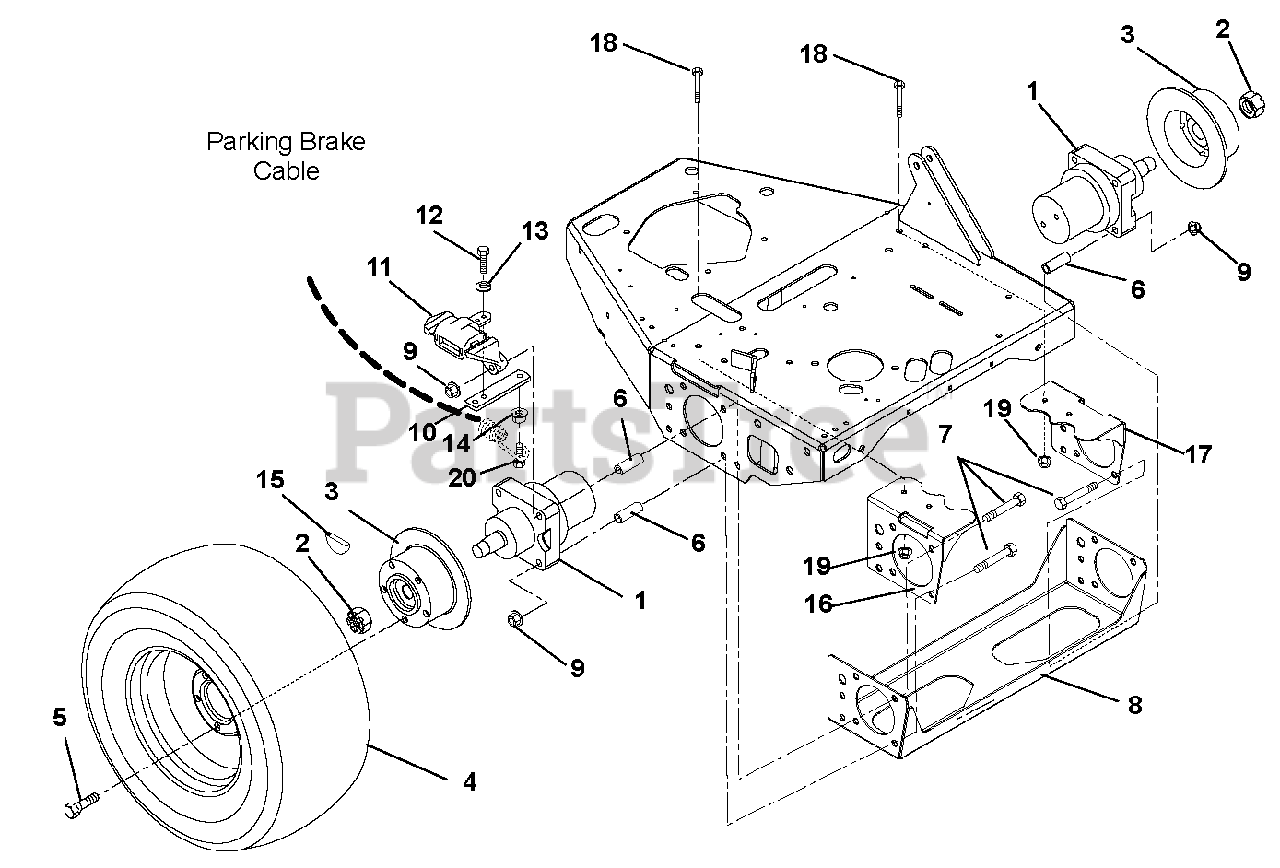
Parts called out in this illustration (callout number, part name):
1	Motor, Hydraulic Wheel (see page 8)
2	Nut, Locking Jam Patch 1.00-20
3	Hub and Disc
4	Tire/Wheel Assembly 24 x 11.50-12
5	Bolt, Lug .50-20 x 1.38
6	Bushing, Sleeve .513 x .748 x 2.129
7	Bolt, Hex .50-13 x 5.00 Grade 8
8	Weldment, Wheel Support Bracket
9	Nut, Locking Top Flange .50-13
10	Arm, Extension Parking Brake
11	Caliper, Park Brake (Clockwise) RH
11	Caliper, Park Brake (Counterclockwise) LH
12	Bolt, Hex .31-18 x .75 Grade 5
13	Washer, Locking .31 x .078
14	Nut, Spin Locking-Flange .312-18
15	Pad, Disk Brake
16	Weldment, Main Frame Brace RH
17	Weldment, Main Frame Brace RH
18	Bolt, Hex .38-16 x .75 Grade 5
19	Nut, Locking Top Flange .38-16
20	Bolt, Hex .31-18 x 1.00 Grade 5 YWZ
